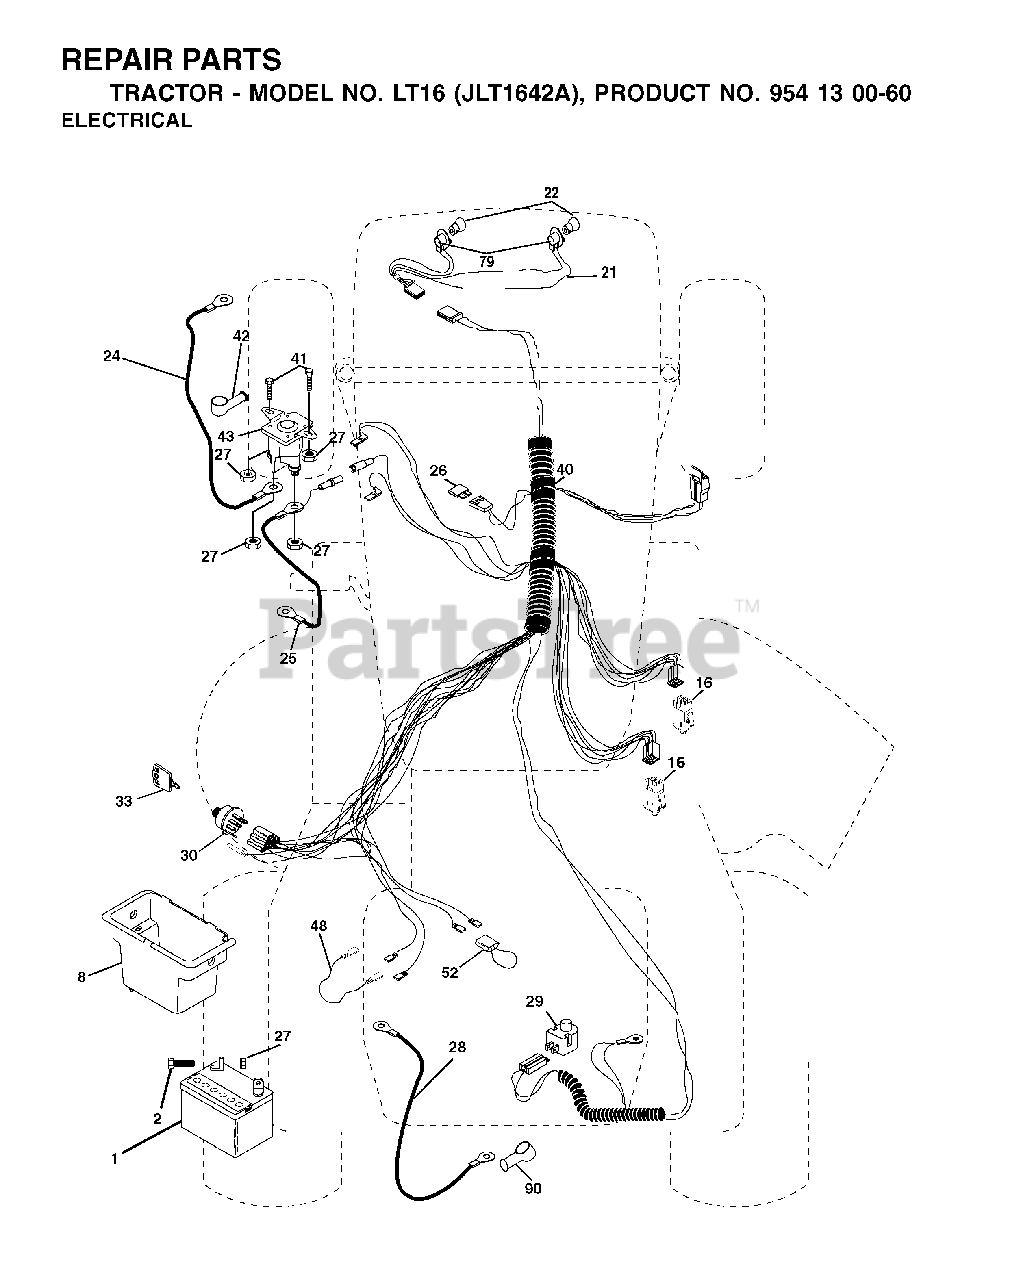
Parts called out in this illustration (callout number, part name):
1	REPL BY 532 12 38-99
8	BOX.BATTERY.FENDER
16	SWITCH INTERLOOK PUSH-IN
21	HARNESS.W/LIGHT SOCKET
22	LIGHTBULB
24	BATTERY CABLE GT
25	CABLE BATTERY
26	FUSE 20AMP
27	NUT
28	CABLE T
29	SWITCH SEAT
30	IGNITION SWITCH
33	KEY MLD GEN DELTA
40	HARNESS.IGNITION
42	TERMINAL COVER
43	SOLENOID
52	WIRE PROTECTION LOOP
89	COVER TERMINAL
